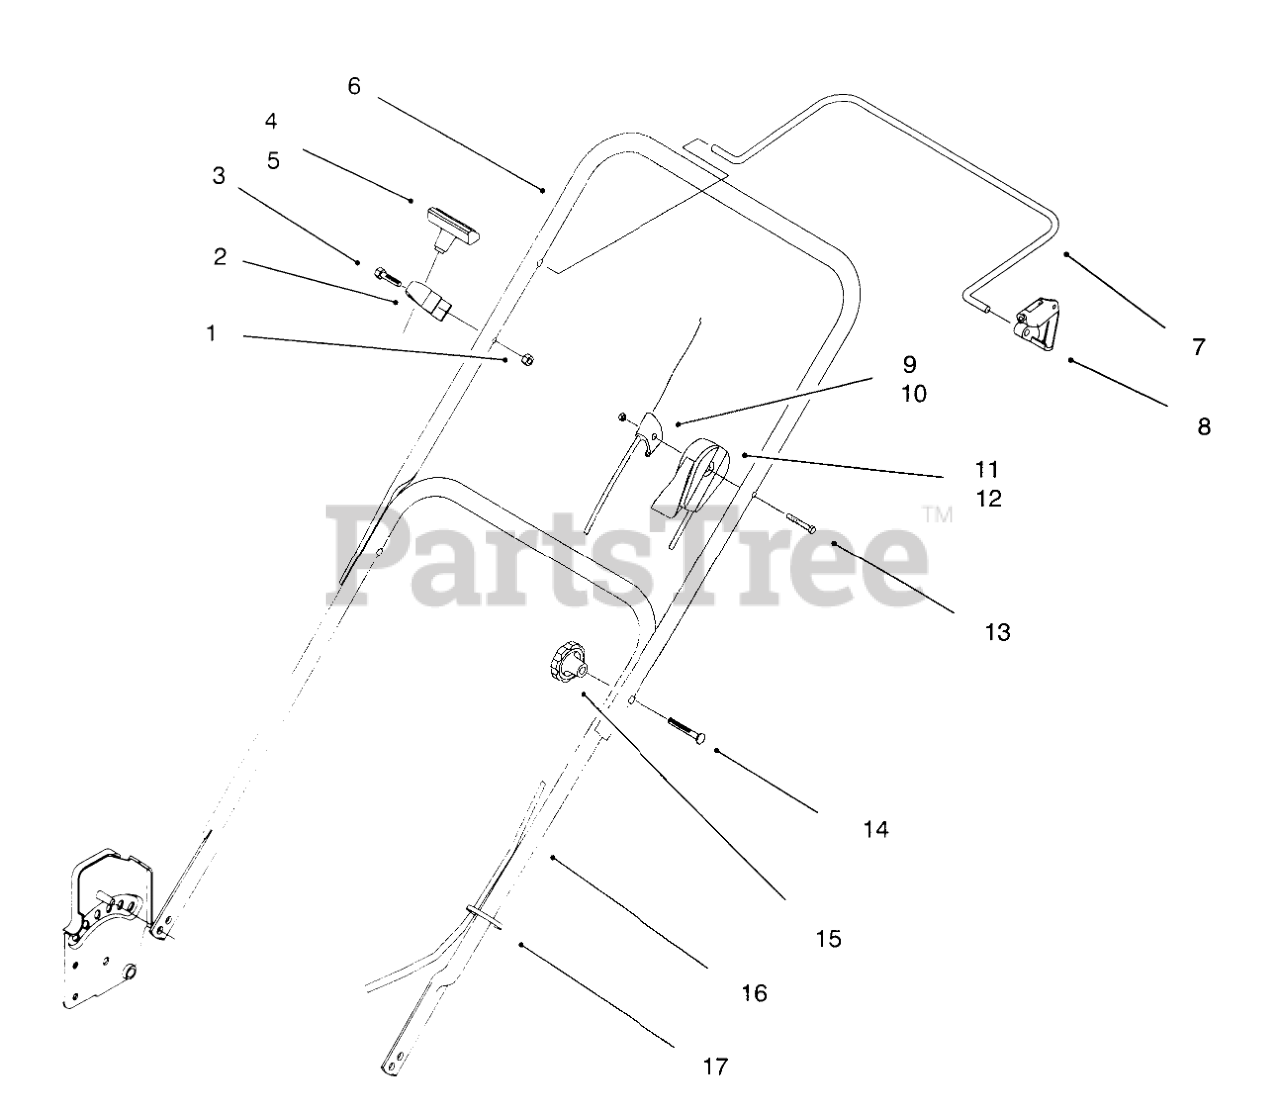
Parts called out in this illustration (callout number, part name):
1	NUT-LOCK, NI
2	GUIDE-ROPE
3	SCREW-HH
4	HANDLE-START
5	CLIP-STARTER
6	Handle-Upper
7	Bar-Control
8	STOP-PIVOT
9	CABLE - BRAKE
10	CABLE-BRAKE SERVICE
11	CABLE - THROTTLE
12	CABLE-THROTTLE
13	SCREW-HANDLE
14	SCREW-HANDLE
16	Handle-Lower
17	TIE-CABLE
